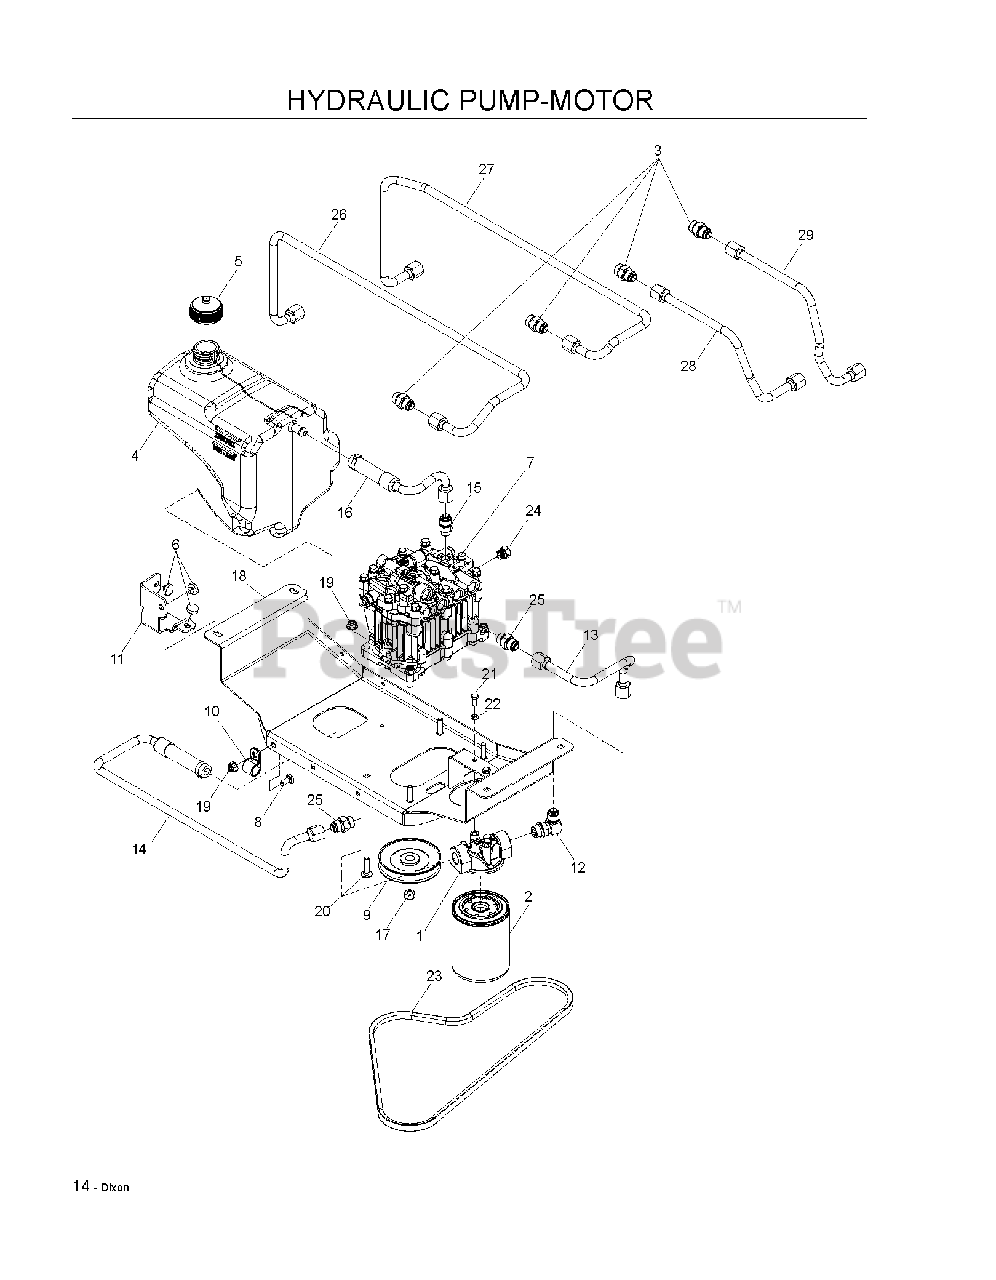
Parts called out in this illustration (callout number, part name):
1	FILTER HEAD
2	HYDRAULIC OIL FILTER
3	FITTING, STRAIGHT F6400-8-8-0
4	RESERVOIR HYDRO
5	HYDRAULIC CAP
6	GROMMET, BUMPER
7	PUMP, DUP10S (77808041201)
8	BOLT 5/16C X 3/4" CARRIAGE
9	PULLEY, PUMP
10	LOOM CLIP
11	SUPPORT, RESERVOIR
12	FITTING, 10-8 90 DEG
13	HYD LINE, CHARGE
14	HYD LINE, INLET
15	FITTING, HYDRO
16	HYDRO LINE, CASE
17	NUT M10-1.5 L/H HEX
18	PLATE, PUMP
19	5/16-18 NYLOC FLANGE NUT
20	BOLT, CARRIAGE 5/16X1-1/4
21	HCS 1/4C X 5/8
22	LOCKWASHER 1/4"
23	IZT BELT
24	PLUG, 6408-6
25	FITTING, 10-8 STRAIGHT
26	HYDRO LINE, A
27	HYDRO LINE, B
28	HYDRO LINE, C
29	HYDRO LINE, D
